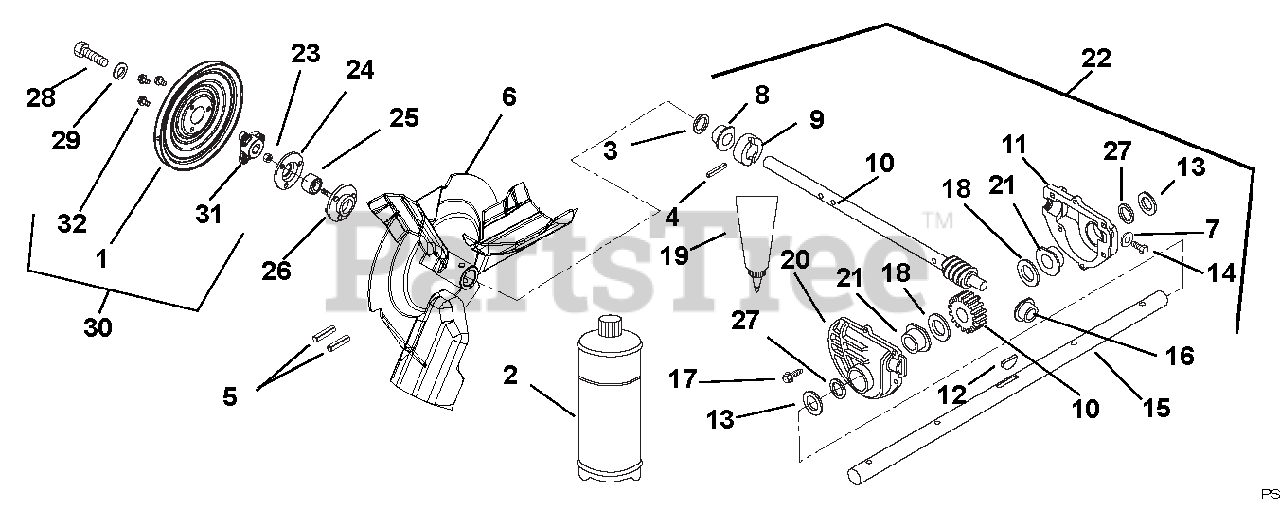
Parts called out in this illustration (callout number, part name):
1	PULLEY,SPIN FORM SINGLE GROOVE
2	ARIENS L3 LUBE, 8 OZ BOTTLE
3	SEAL-OIL.748X1.378X.276 RBR OD
4	@PIN-GRV .188X1.25 TP E ALLOY
5	PIN-ROLL .250X1.75
6	IMPELLER, COMPACT 12" 3-BLADE
7	WSHR-FIBER .437X.656X.032
8	BSHG-FLG .750X1.000X.750X1.250
9	THRUST COLLAR, .75" ID
10	SHAFT AND WORM GEAR ASSEMBLY
11	GEARCASE CASTING, MACHINED LH
12	KEY-WDRF .19X.63 HRD #61
13	@WSHR-FL-STL.812X1.50X.135YWZC
14	SCR-TAP .38-16X.75 ROLOK YZ WX
15	SHAFT, RAKE - 24" (.750 DIA)
16	BSHG-FLG .502X1X.750
17	@SCR-TAP .25-20X1.00 HWH TR YZ
18	WSHR-FL-STL.755X1.375X.062YWZC
19	LOCTITE 518 GASKET--6ML TUBE
20	GEARCASE CASTING, MACHINED RH
21	BSHG-FLG .753X1.127X.500X1.501
22	GEARCASE, 24" ALUM, SMALL CD
23	@NUT-LK-CTR .25-20 YWZC
24	BEARING FLANGE
25	BRG-BALL .750X1.750X.50
26	BEARING FLANGE
27	SEAL-OIL .750X1.375X.250
28	BLT-HEX .31-24X.75 YWZC GR5
29	WSHR-LK .312X.097 HVY YWZC
30	PULLEY WITH HUB
31	PULLEY HUB, BOLT-ON D-BORE .75
32	@SCR-TAP .31-18X.50 HWH TR YWZ
